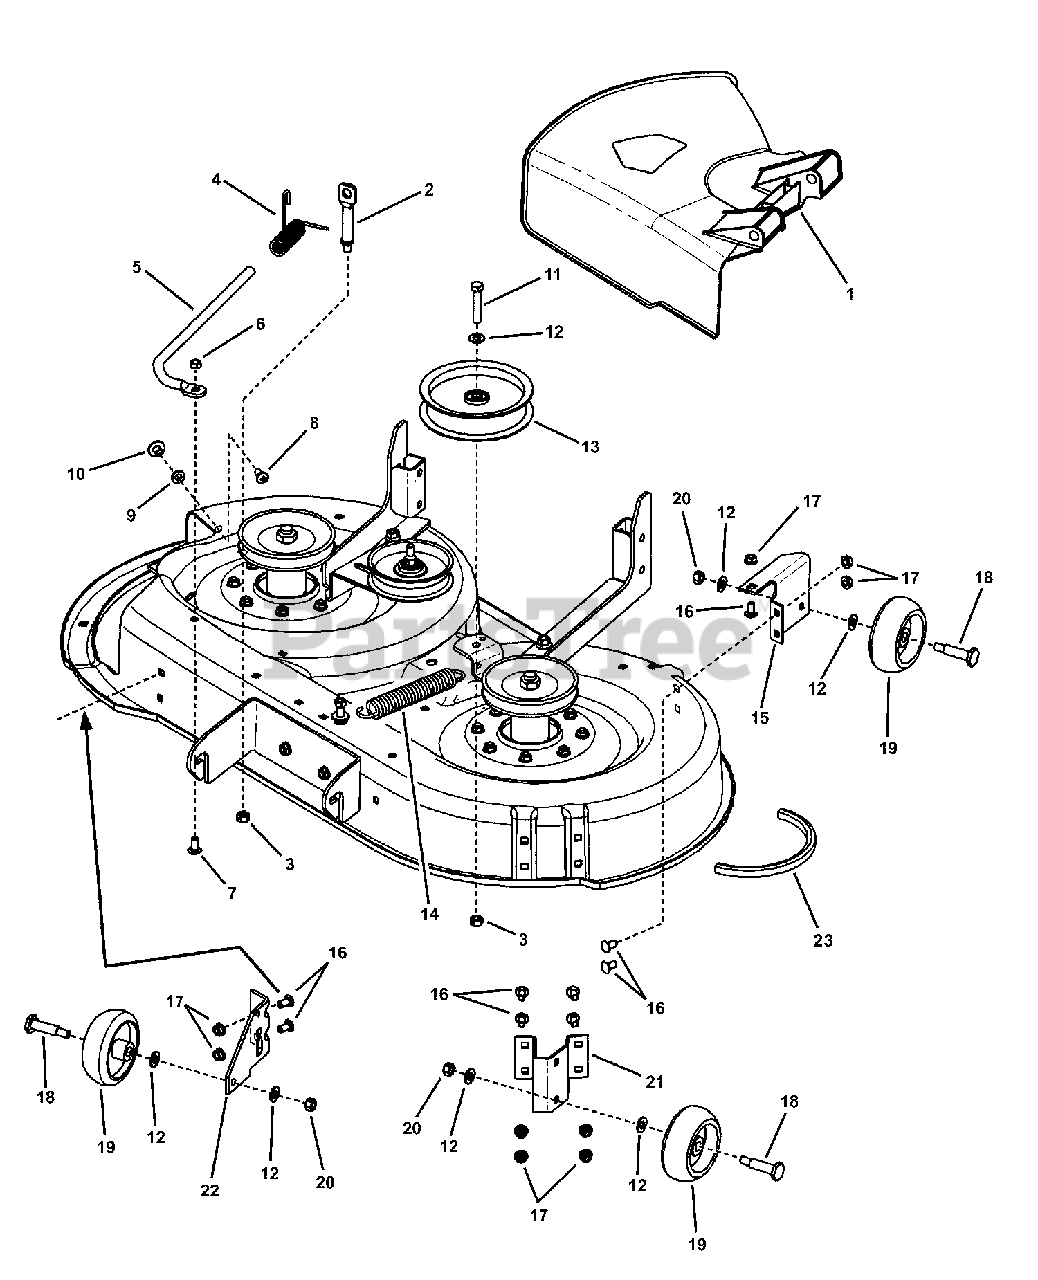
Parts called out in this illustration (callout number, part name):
1	DISCHARGE CHUTE, 38" Deck
2	ROD, Mounting, Side Discharge (3/8-16 thread)
3	NUT, 3/8-16 Hex Center Lock, GR 5 or B, YZ
4	SPRING, Torsion-Side Discharge-38 Deck
5	ROD, Pivot, Side Discharge, 38 Deck
6	NUT, 5/16-18 Hex Center Lock, GR 5 or B, YZ
7	BOLT, 5/16-18 x 3/4" Short Neck Carriage, GR 5
8	SCREW, 5/16-18 x 5/8" Cross Recessed Pan Head
9	WASHER, .34 x .69 x .08 Flat
10	TEENUT, 5/16-18 Thread
11	SCREW, 3/8-16 x 2" Hex Head Cap, GR 5, YZ
12	WASHER, 3/8" Flat SAE
13	PULLEY, Flat Idler, 5" Dia.
14	SPRING, Extension, 1.03 Dia. x 6.8 Long
15	GAGE WHEEL BRACKET, LH Rear
16	BOLT, 5/16-18 x 3/4" Short Square Neck Carriage, GR 5
17	NUT, 5/16-18 Hex Flange Lock, GR 5
18	SHOULDER BOLT, 3/8-16 x 5/8" GR 5 YZ
19	GAGE WHEEL 4 x 1-7/8" Offset
20	NUT, 3/8-16 Hex Center Lock
21	BRACKET, Front Gage Wheel (Cardinal Red)
22	BRACKET, Right Front Gage Wheel (Cardinal Red)
23	BELT, A Section, Effective Length 114"
